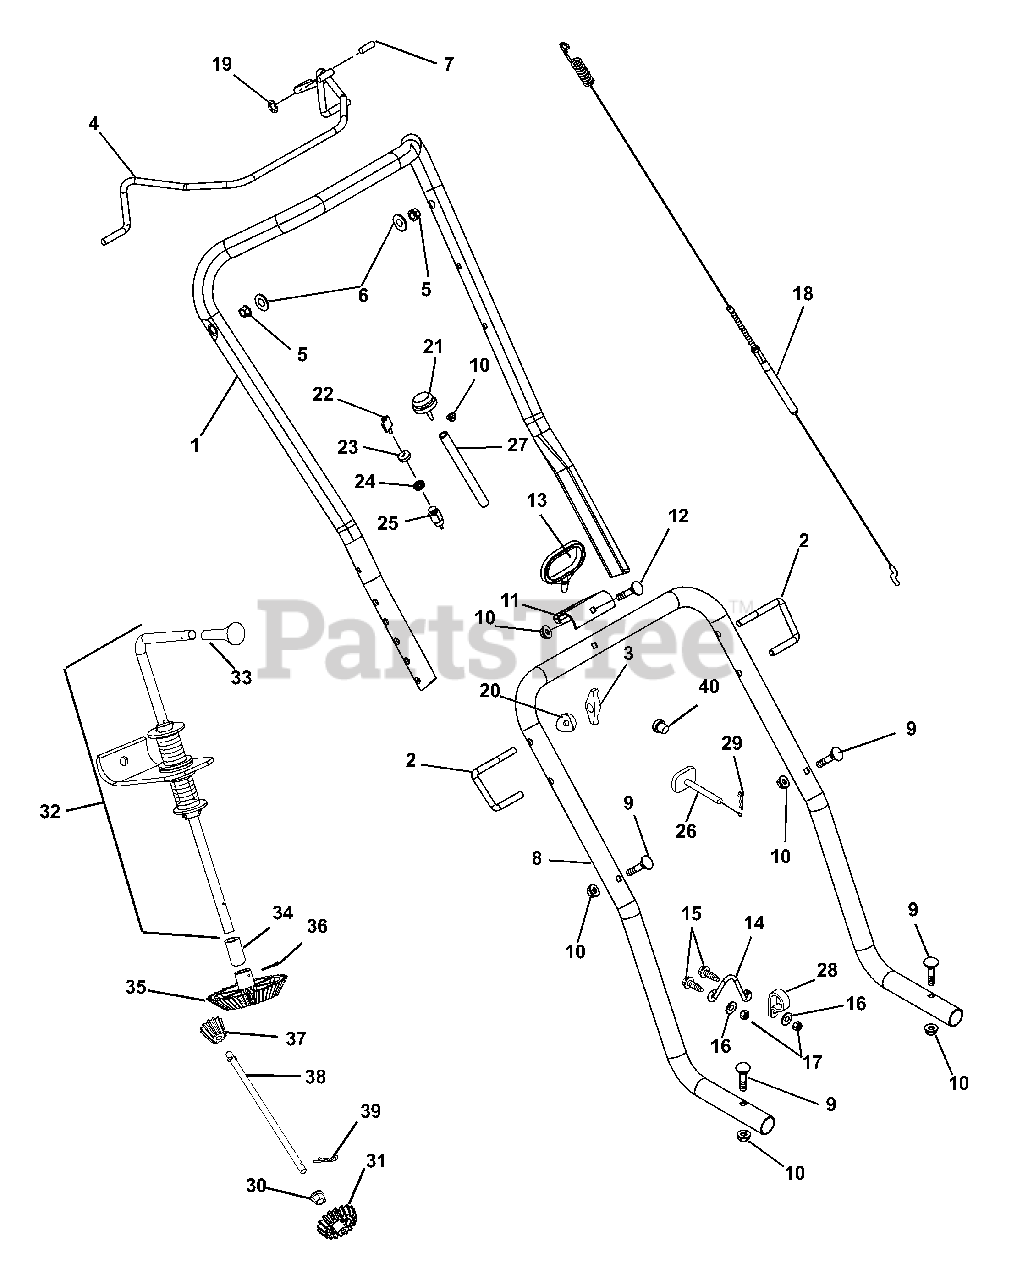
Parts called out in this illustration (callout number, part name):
1	HANDLEBAR, UPPER
2	J BOLT .31-18
3	KNOB - WING .312-18 UNC
4	BAIL SS LF
5	BSHG-FLG .325X.444X.440X.560
6	@WSHR-FL-STL.344X.688X.065YWZC
7	CAP, VINYL, .25 ID
8	HANDLEBAR, LOWER, SS522/SS722
9	BLT-RDHDSQNK .25-20X1.75 G5YZ
10	NUT-LK-FLG .250-20 PL BLK
11	BRKT-STARTER HANDLE
12	BLT-RDHDSQNK .25-20X1.50 PL BL
13	HANDLE, RECOIL START
14	ROPE GUIDE
15	@SCR-MCH 10-24X1.00 HWH YWZC
16	@WSHR-FL-STL.219X.50X.049 YWZC
17	@NUT-LK-NYL 10-24 W/INSRT YWZC
18	CABLE-CLUTCH CONTROL
19	RG-RTNG-EXT .250X.010
20	SPACER, HANDLEBAR
21	PRIMER ASSY
22	KEY -W/CAP
23	CAP - IGNITION SWITCH
24	NUT-PANEL .625-32 GRECO
25	SWITCH ASSEMBLY
26	CONTROL, CHOKE 5&7HP TEC 2CYCL
27	LINE-PRIMER
28	CLAMP, NYLON .5 HOSE
29	PIN-HAIR, ENDRIES #25 YWZC
30	BSHG-FLG .325X.444X.440X.560
31	PINION-DISCHARGE CHUTE 18T
32	CRANK-CHUTE ASSY
34	BSHG-SLV .510X.753X2.00
35	GEAR-CRANK TRANSFER 48T
36	@PIN-CTR .16X1.25 EXTPRSQCT YZ
37	PINION-CRANK TRANSFER 12T
38	SHAFT CHUTE CRANK TRANSFER
39	HAIRPIN, INTERNAL .08X.32X1.96
40	PLUG-HOLE .50 DIA
